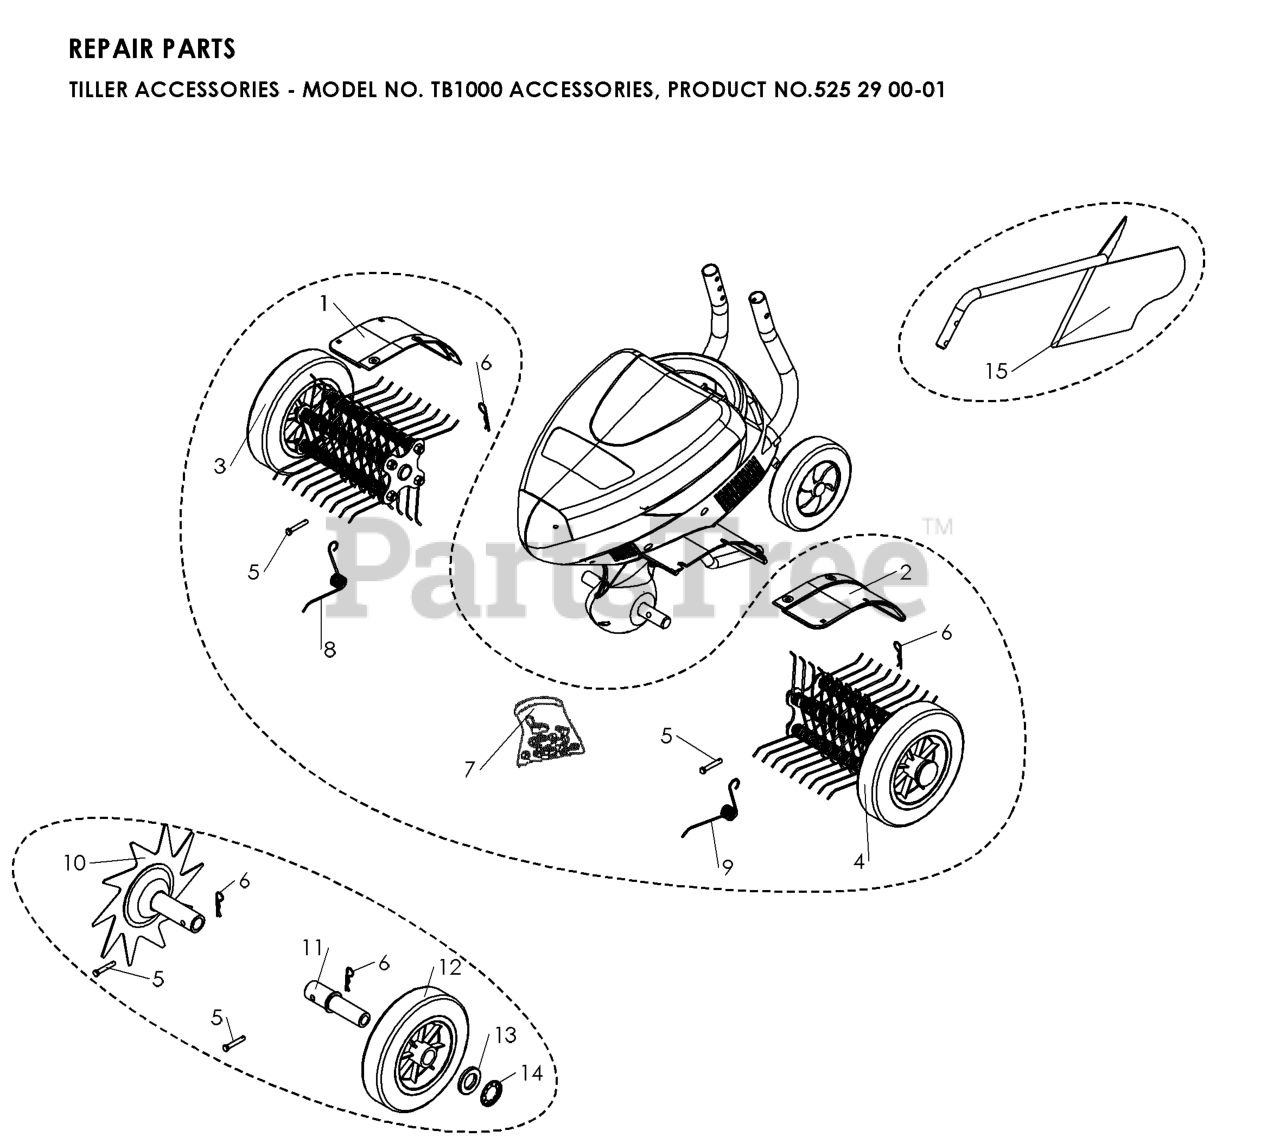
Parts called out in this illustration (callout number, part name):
1	DECAL.AUGER.SAFETY.
3	DECAL.CHUTE.SAFETY.
4	DECAL.AUGER."
6	DECAL.CONSOLE.INSTRUCTION
12	DECAL.BELT.GUARD.
13	DECAL, HUSQVARNA
14	DECAL.NOISE.LEVEL.108DB/CE.INT
